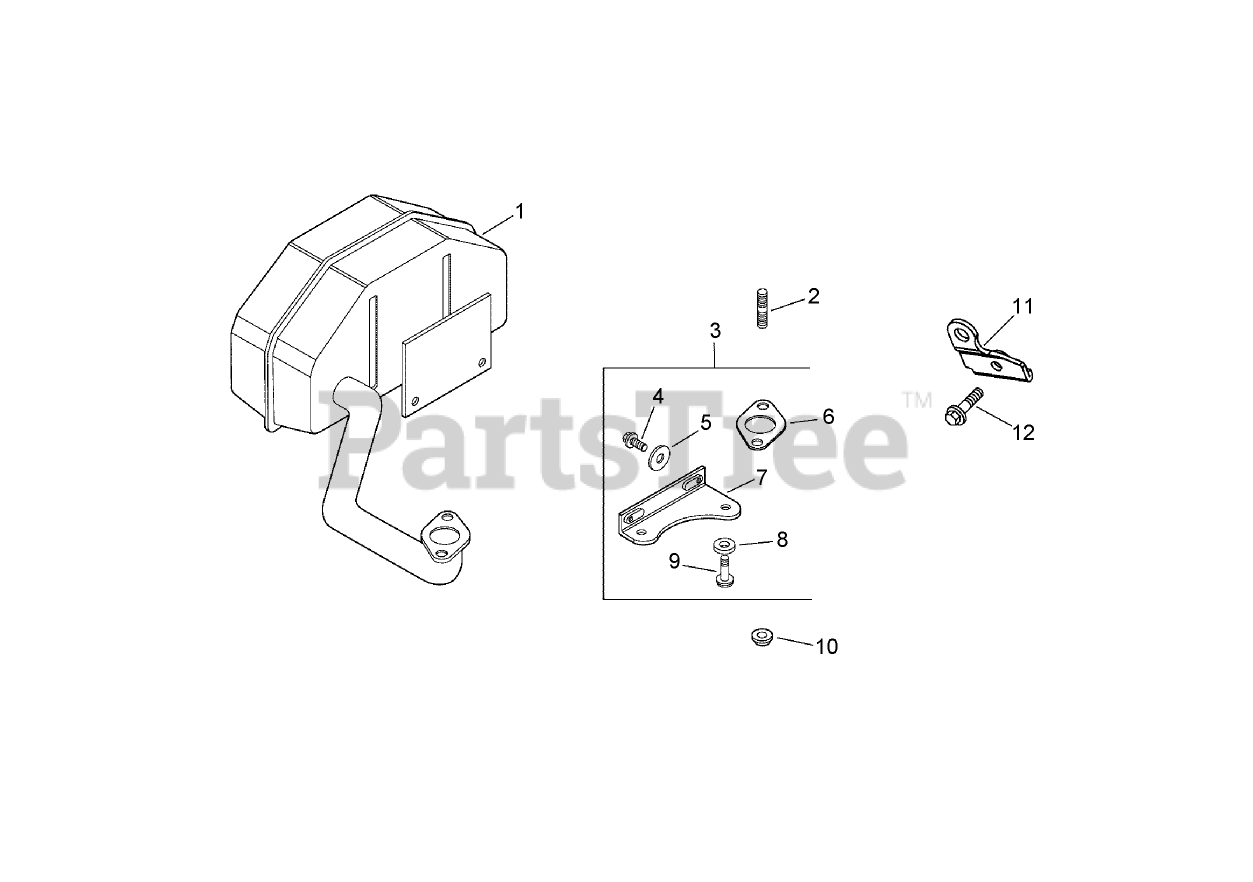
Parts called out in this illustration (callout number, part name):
1	Muffler
2	STUD (M8X1.25X33)
3	Bracket-Kit (Incl. Ref. #4-9)
4	Screw-HF (M6x1.0x12)
5	Washer-Flat (1/4)
6	Gasket-Manifold, Exhaust
7	Bracket-Muffler
8	Washer
9	Screw-HF (M8x1.25x 50)
10	NUT-FLANGE (M8X1.25)
11	Bracket-Strap, Lifting
12	SCREW-HHFTF (M6X1.0X20)
